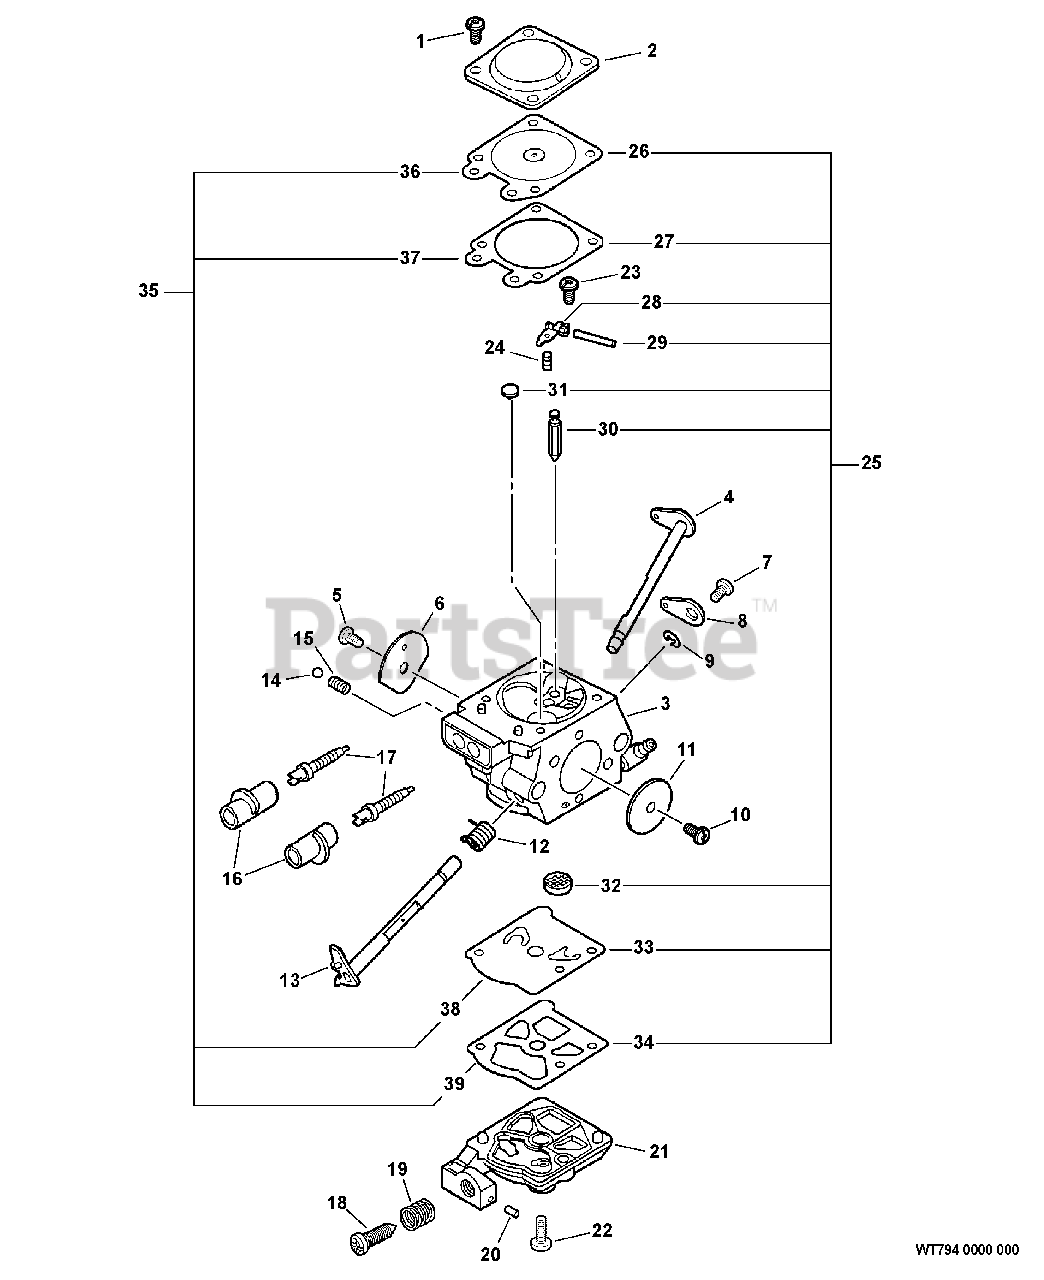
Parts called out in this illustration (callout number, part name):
2	COVER, METERING DIAPHRAGM
3	BODY, CARBURETOR
4	SHAFT, CHOKE
6	VALVE, CHOKE
8	LEVER, THROTTLE
11	VALVE, THROTTLE
12	SPRING, THROTTLE RETURN
13	SHAFT, THROTTLE
15	BALL, CHOKE FRICTION
16	CAP, LIMITER
17	NEEDLE, MIXTURE
18	SCREW, IDLE ADJUST
19	SPRING, IDLE ADJUST
20	PLUG, FRICTION
21	COVER, FUEL PUMP
23	SCREW, METERING LEVER PIN
24	SPRING, METERING LEVER
25	REPAIR KIT, CARBURETOR
26	DIAPHRAGM, METERING
27	GASKET, DIAPHRAGM
28	LEVER, METERING
29	PIN, METERING LEVER
30	VALVE, INLET NEEDLE
31	PLUG, WELCH
32	STRAINER
33	DIAPHRAGM, PUMP
34	GASKET, PUMP
35	GASKET / DIAPHRAGM KIT
36	DIAPHRAGM, METERING
37	GASKET, DIAPHRAGM
38	DIAPHRAGM, PUMP
39	GASKET, PUMP
